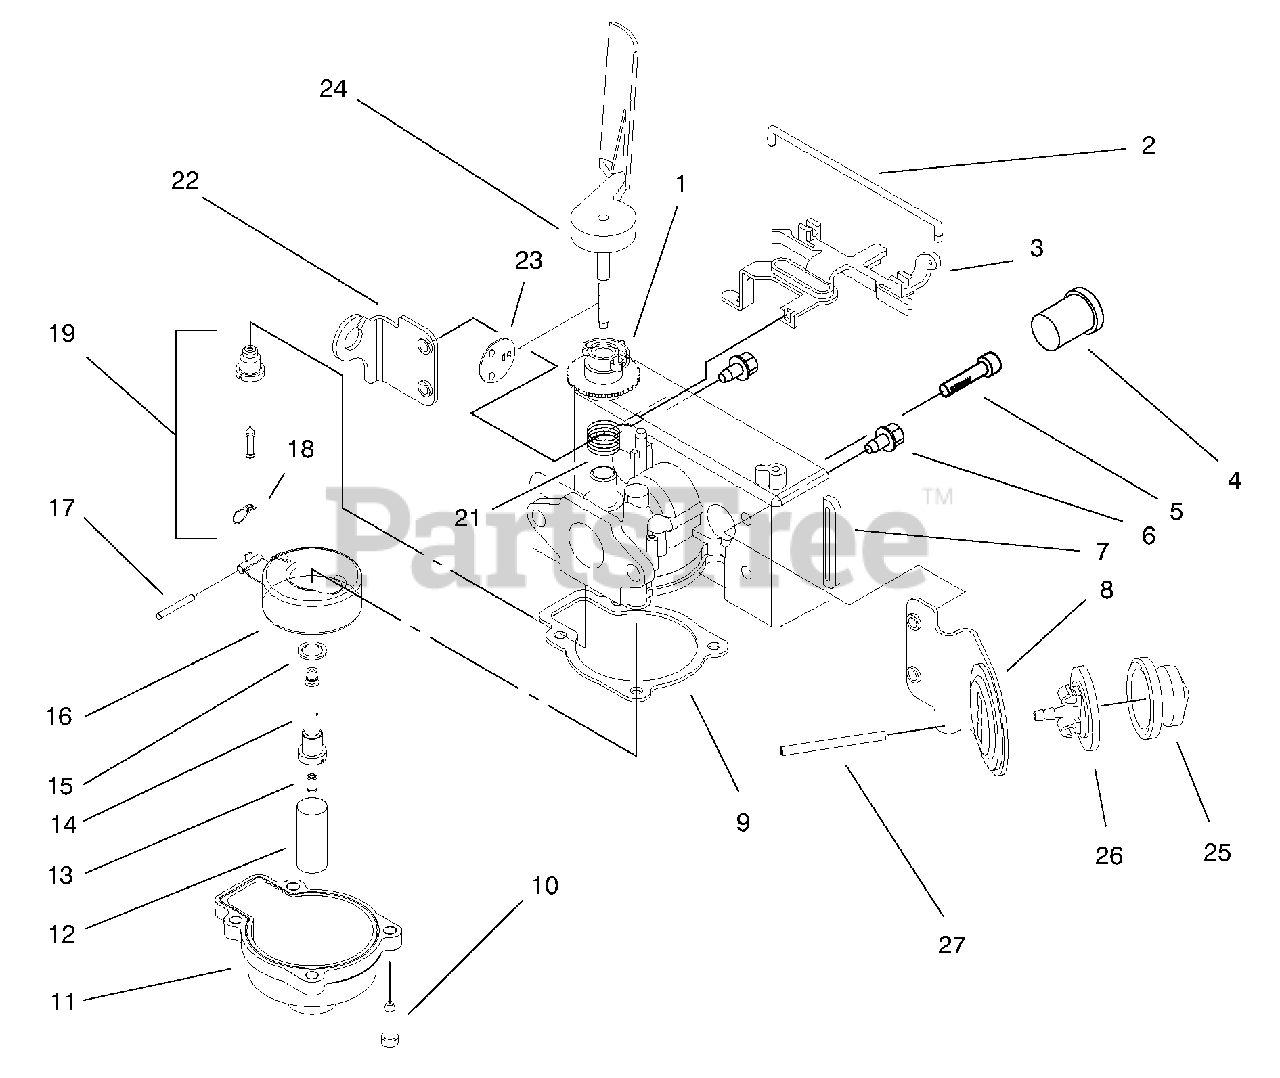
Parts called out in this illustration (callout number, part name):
1	Collar-Adjustment
2	Retainer
3	Lever-Speed Adjust
4	Plug
5	Screw-Pan Hd. Sems
7	Body-Carburetor
8	Bracket-Primer
9	Gasket-Float Chamber
11	Float Chamber
12	Filter-Fuel
13	Main Jet
16	Float & Arm Assembly
18	Clip
19	Float, Valve, & Body Ass'y
21	Spring-Governor
22	Bracket-Throttle Control
23	Disc-Throttle
24	Air Vane & Shaft
25	Bulb-Primer
26	Body-Primer
27	Hose-Primer
